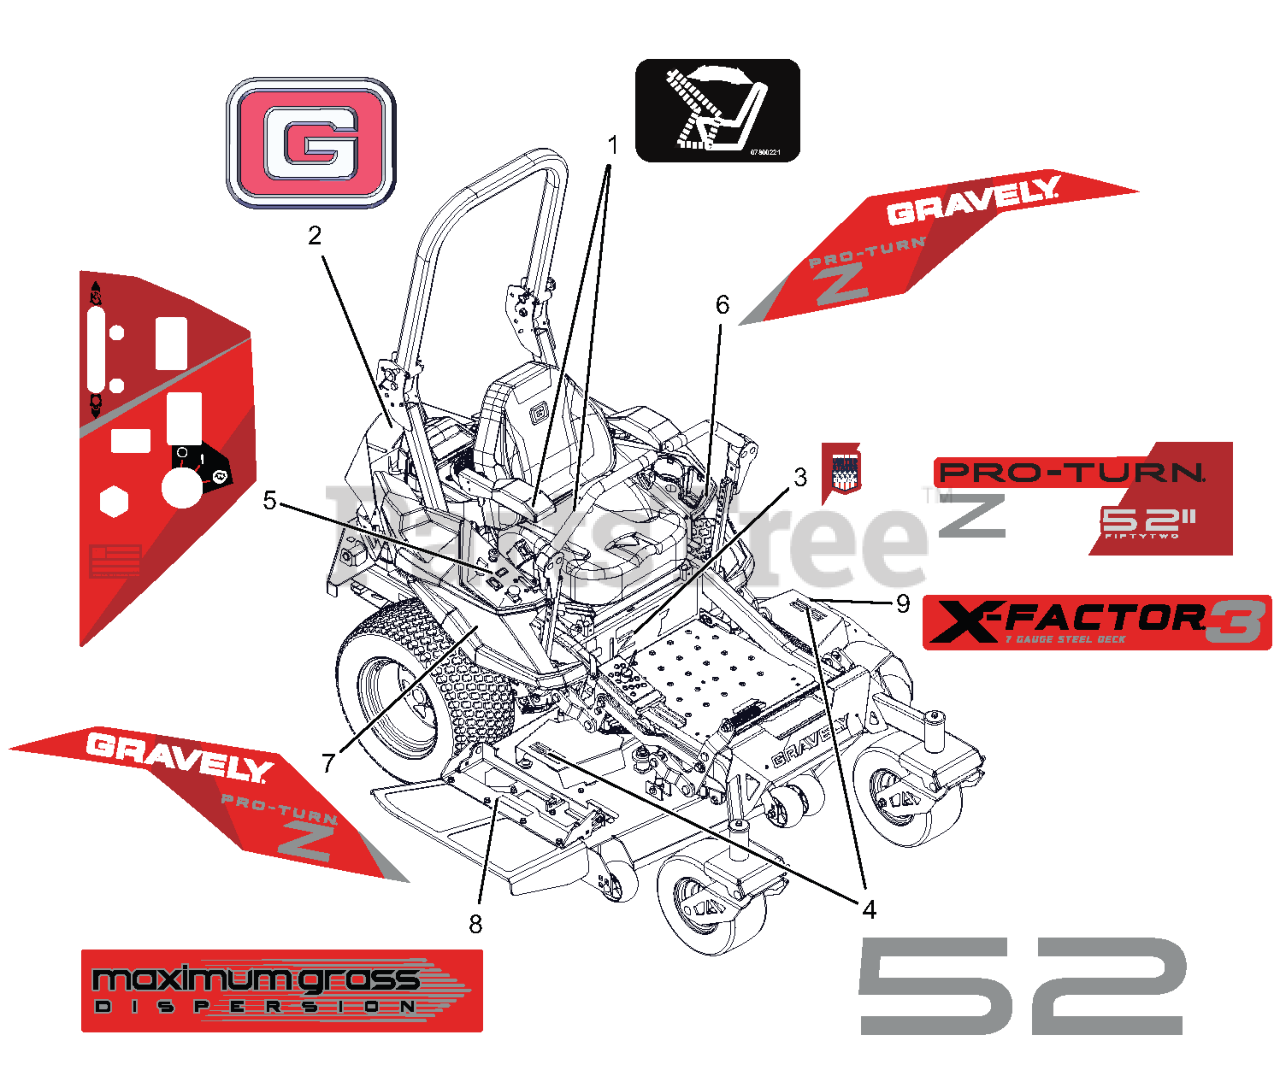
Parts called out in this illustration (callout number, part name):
1	DECAL - SEAT RELEASE
2	DECAL, GRAVELY BRAND
3	DECAL-PTZ 52
4	DECAL, DECK - 52
5	DECAL, CONTROL PANEL
6	DECAL, FENDER LH - PTZ
7	DECAL, FENDER RH - PTZ
8	DECAL, DECK - MAX GRASS
9	DECAL, DECK - X-FACTOR 3 7 GAUGE
